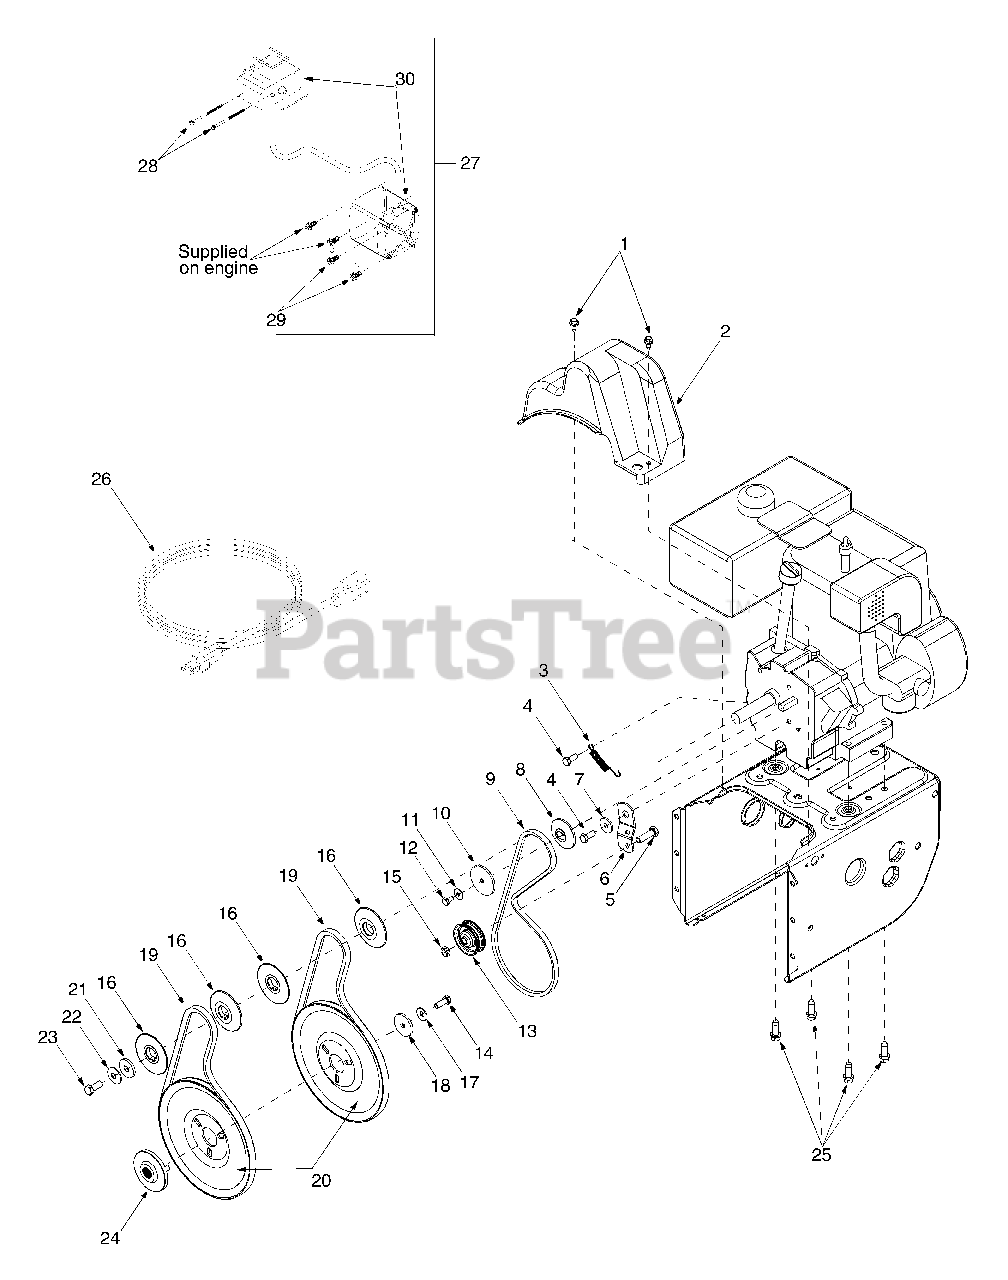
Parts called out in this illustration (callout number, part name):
1	Hex Washer Screw 1/4-20 x.625
2	Belt Cover
3	Extension Spring
4	Hex Screw 5/16-24 x.75
5	Hex Cap Screw 3/8-16 x 1.25
8	Pulley Half
9	V-Belt
10	Pulley Half
11	Bell Washer
12	Hex Cap Screw 1/4-28 x.50
13	Flat Idler
14	Lock Hex Cap Screw 5/16-24
15	Lock Jam Nut 3/8-16
16	Pulley Half
17	Bell Washer
18	Flat Washer
19	Belt
20	Auger Pulley
21	Flat Washer 3/8 x 1.25 OD
22	Bell Washer
23	Hex Cap Screw 3/8-24
24	Adapter Pulley
25	Hex Screw 3/8-16 x 1.0
26	Extension Cord
27	Electric Start Kit
28	Hex Screw #6-32 x 2.5
29	Hex Screw 1/4-20 x.500
30	Electric Starter
31	Engine Shroud Assembly
32	Screw #10-16 x.75
33	Flange Lock Nut 5/16-18
